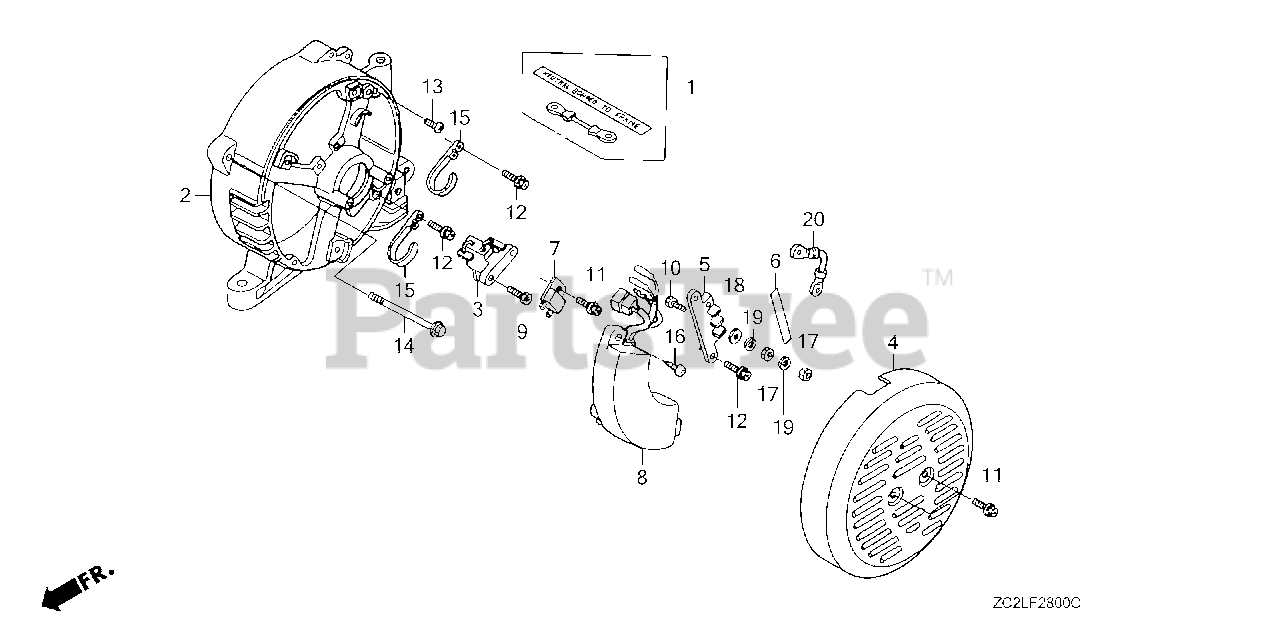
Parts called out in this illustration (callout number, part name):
2	HOUSING, RR. (NA USE ALT:31108-ZB4-631)
3	BRUSH ASSY.
4	COVER, GENERATOR END *NH105* (MAT BLACK)
5	TERMINAL, VOLT CHANGE
6	MARK, VOLT
7	DIODE, D.C.
8	REGULATOR ASSY., AUTOMATIC VOLTAGE
9	SCREW, TAPPING (5X18)
10	BOLT, HEX. (5X20)
11	SCREW, TAPPING (5X12)
12	SCREW, TAPPING (5X14)
13	SCREW, PAN (5X12)
14	BOLT, FLANGE (6X160)
15	TIE, CABLE
16	SCREW, TAPPING (5X16)
17	NUT, HEX. (5MM)
18	WASHER, PLAIN (5MM)
19	WASHER, SPRING (5MM)
